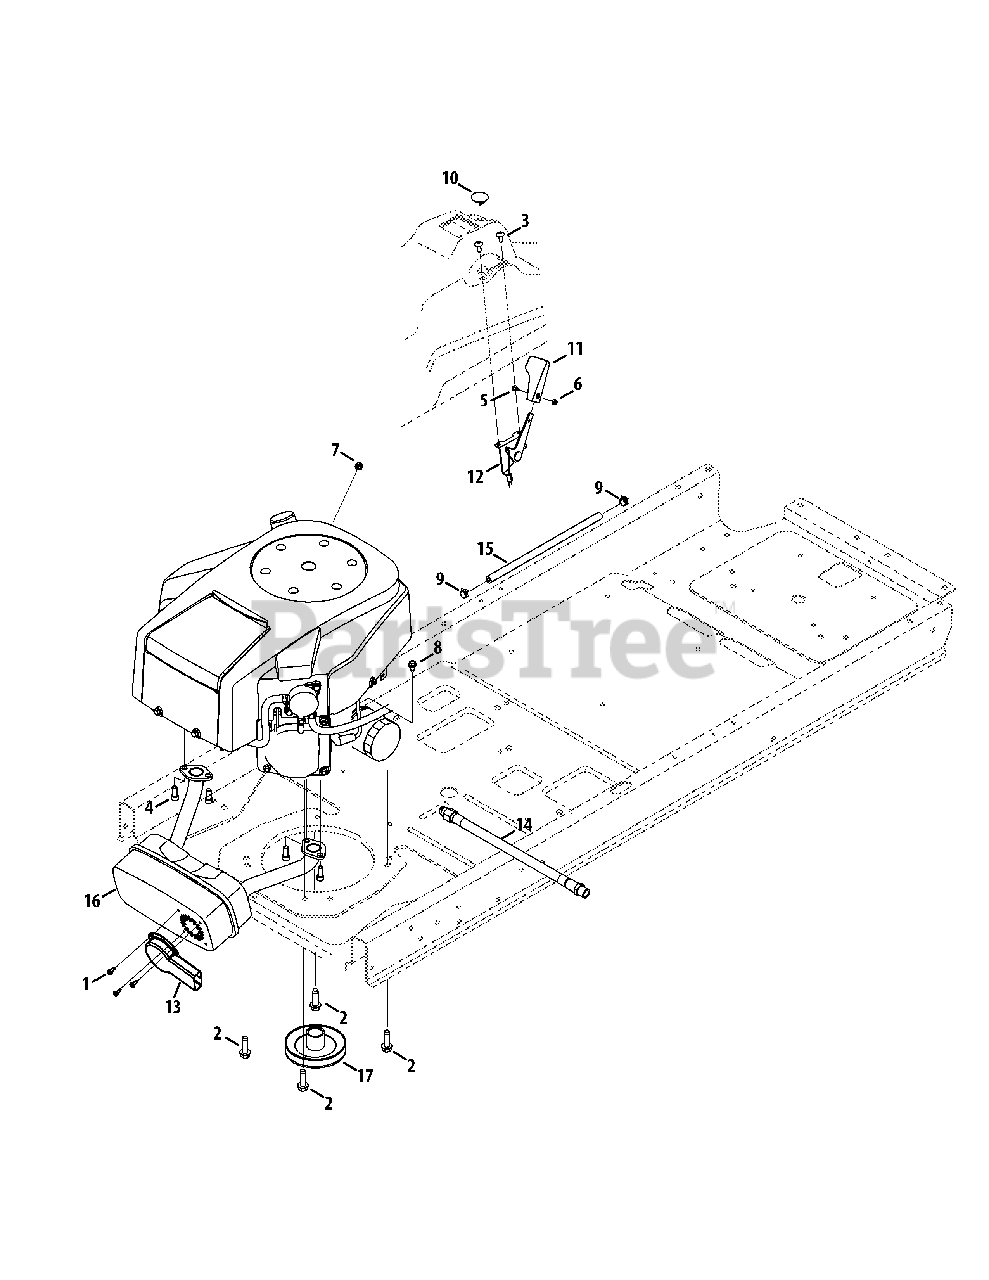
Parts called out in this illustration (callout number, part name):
1	Hex Washer Screw, #8-18 x .500
2	Hex Washer Screw, 3/8-16 x 1.00
3	Screw, 1/4-20 x .50
4	Socket Head Screw, 5/16-18 x .750
5	Screw, #8-32 x .375
6	Hex Nut, #8-32
7	Flange Lock Nut, 1/4-20
8	Hex Washer Screw, 1/4-20 x .625
9	Hose Clamp, .490 Dia.
10	Choke Plug
11	Throttle Control Knob
12	Throttle/Choke Control Cable
13	Muffler Deflector Long
14	Oil Drain Hose
15	Fuel Hose, 1/4
16	Twin Muffler
17	Engine Pulley
